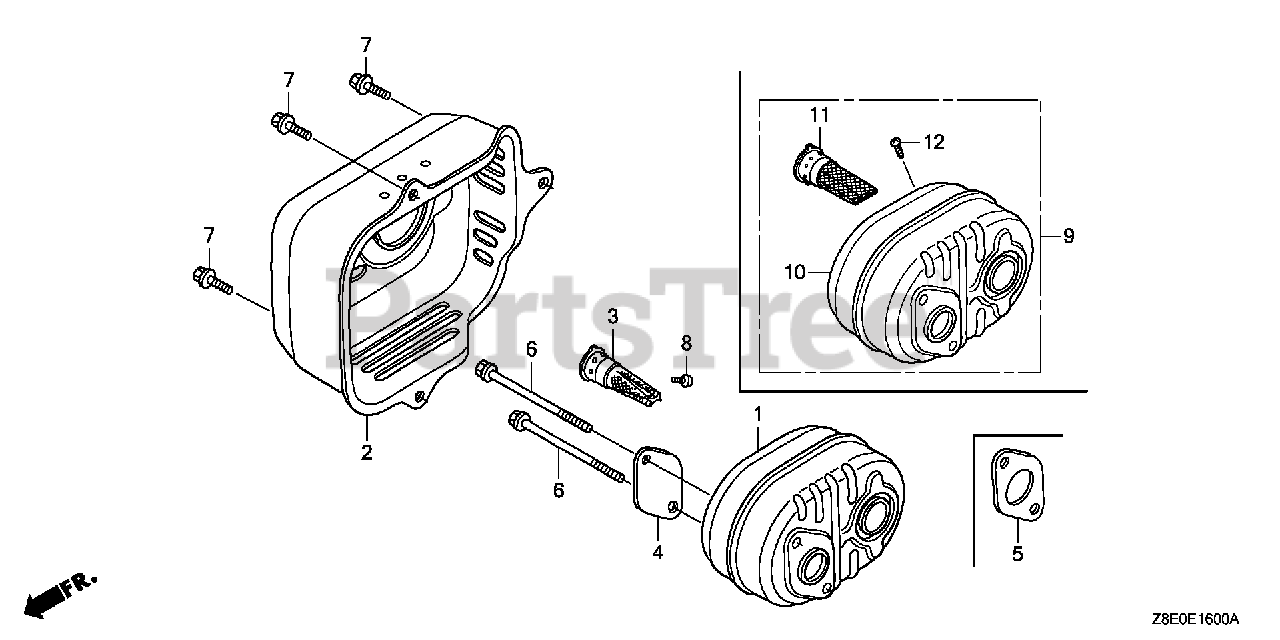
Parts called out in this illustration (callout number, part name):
1	MUFFLER
2	PROTECTOR, MUFFLER
3	ARRESTER, SPARK (TO 1207644)
4	PLATE, ARRESTER NUMBER (TO INSTALL OPTIONAL SPARK ARRESTER)
5	GASKET, MUFFLER
6	BOLT, FLANGE (6X79) (CT200)
7	BOLT, FLANGE (6X12) (CT200)
8	SCREW, TAPPING (4X6) (TO INSTALL OPTIONAL SPARK ARRESTER)
9	MUFFLER ASSY. (ARRESTER)
10	MUFFLER
11	ARRESTER, SPARK
12	SCREW, TAPPING (4X6) (TO INSTALL OPTIONAL SPARK ARRESTER)
